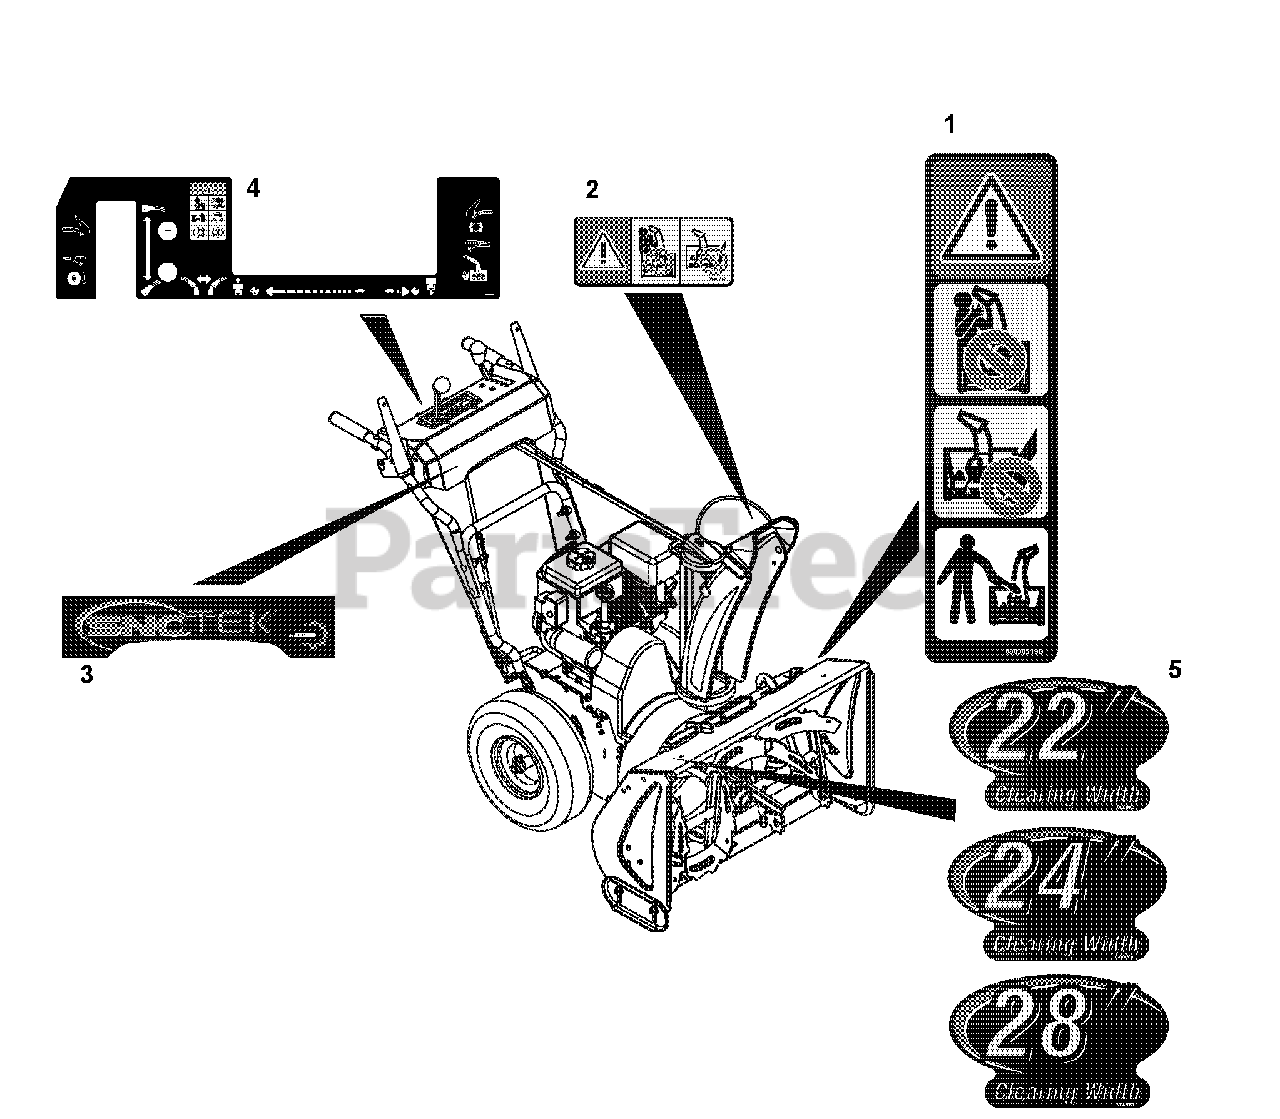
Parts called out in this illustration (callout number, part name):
1	DECAL, DANGER - ROTATING PARTS
2	DECAL, DANGER SNO-TEK
3	DECAL, DASH - SNO-TEK
4	DECAL,CONTROL - COMPACT REMOTE
4	DECAL,CONTROL - COMPACT MANUAL
5	DECAL, HOUSING SNO-TEK 24
5	DECAL, HOUSING SNO-TEK 28
5	DECAL, HOUSING SNO-TEK 22
5	DECAL, HOUSING SNO-TEK 20
